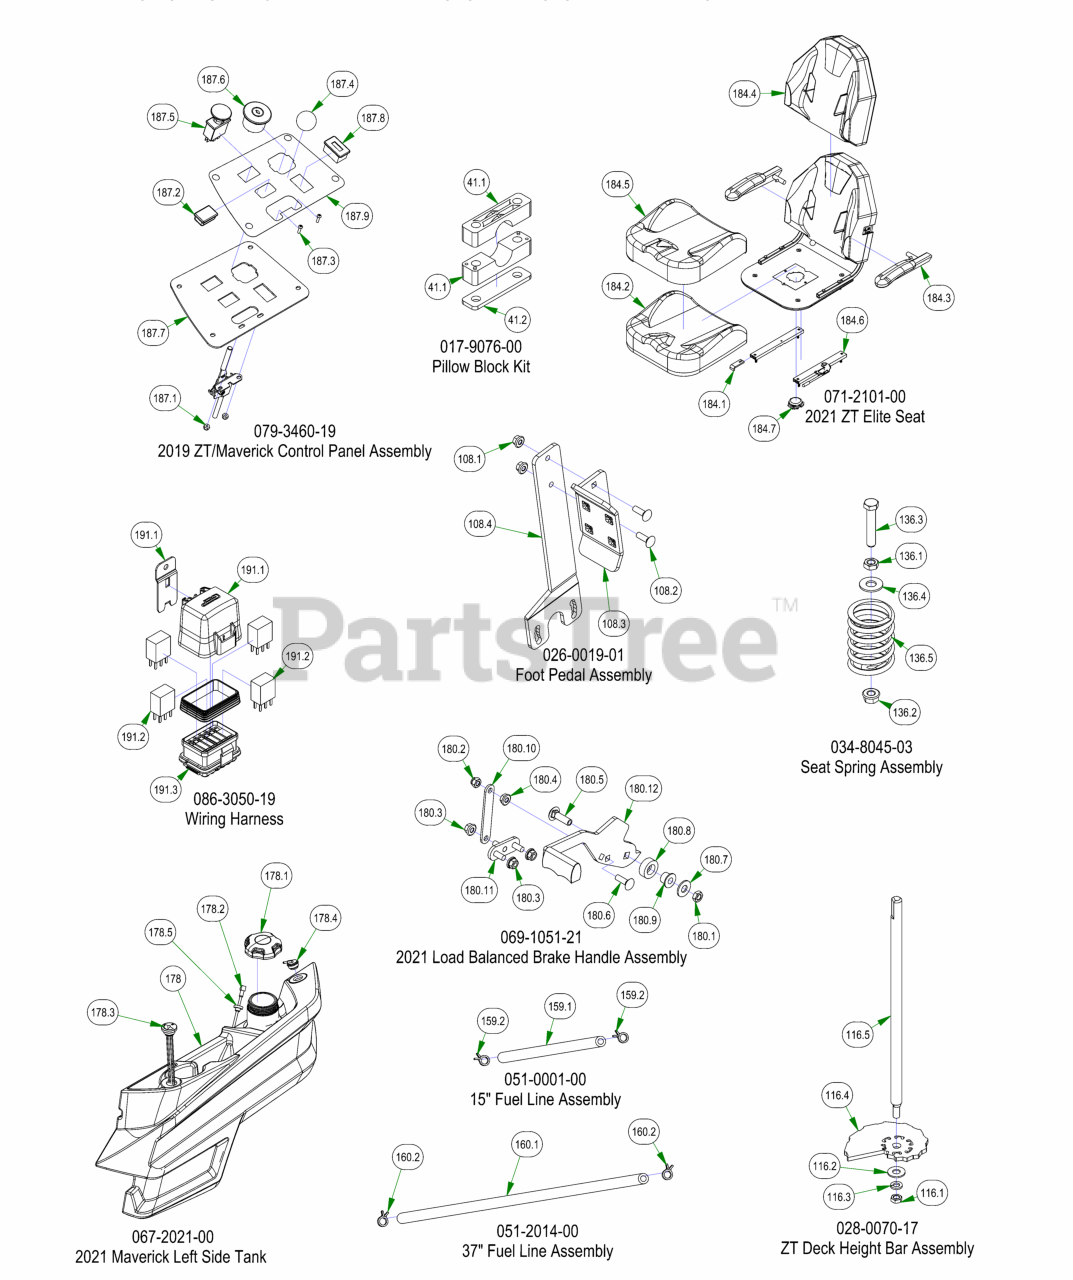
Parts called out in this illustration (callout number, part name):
41	Pillow Block Kit
41.1	Pillow Block MZ
41.2	Pillow Block Strap
108	Foot Pedal Assembly
108.1	5/16-18 NYLON INSERT FLANGE LOCKNUT ZINC
108.2	5/16-18 X 1 CARRIAGE BOLT (GR.8) ZINC
108.3	2017 MZ/ZT Shallow Foot Pedal
108.4	2017 MZ/ZT Deck Pedal Lever
116	ZT Deck Height Bar Assembly
116.1	3/8-24 HEX NUT ZINC YELLOW
116.2	3/8 FLAT WASHER USS (1" OD) ZINC
116.3	3/8 SPLIT LOCKWASHER ZINC
116.4	2017 MZ/ZT Cam Plate
116.5	2017 Deck Height Dial Rod ZT
136	Seat Spring Assembly
136.1	3/8-16 Half Jam Nut
136.2	3/8-16 HEX SERRATED FLANGE NUT HARD/ZINC
136.3	3/8-16 X 2 HEX CAP SCREW (GR.5) ZINC
136.4	3/8 FLAT WASHER USS (1" OD) ZINC
136.5	Seat Spring
159	15" Fuel Line Assembly
159.1	1/4 Fuel Line
159.2	1/4 Fuel Hose Clamp
160	37" Fuel Line Assembly
160.1	37" 1/4 Fuel Line
160.2	1/4 Fuel Hose Clamp
178	2021 Maverick Left Side Tank
178.3	Fuel Gauge w/Grommet
178.4	Rollover Valve W/Grommet
178.5	Pick-Up Grommet
180	2021 Load Balanced Brake Handle Assembly
180.1	3/8-16 HEX JAM 2-WAY REVERSIBLE CENTER LOCKNUT ZINC
180.2	5/16-18 NYLON INSERT CAP LOCKNUT ZINC (BLK CAP)
180.3	5/16-18 NYLON INSERT FLANGE LOCKNUT ZINC
180.4	5/16-18 HEX SERRATED FLANGE NUT HARD/ZINC
180.5	3/8-16 X 1-1/4 CARRIAGE BOLT ZINC
180.6	5/16-18 X 1 CARRIAGE BOLT (GR.8) ZINC
180.7	3/8 FLAT WASHER USS (1" OD) ZINC
180.8	2015 Brake Lever Spacer
180.9	.377 ID X .625 OD X .500 HGT X .880 FLNG DIA X .060 FLNG THK
180.10	Brake Cable Extension Plate
180.11	Brake Load Balancer Lower Weldment
180.12	Load Balanced Brake Handle with Grip
184	2021 ZT Elite Seat
184.1	Black Seat stop from Seat King
184.2	Seat Cover Molded Foam for 071-2040-18/071-5080-18
184.3	2017 ZT/Maverick/2020 ZTElite/Avenger Arm Rest Kit
184.4	Back Cover for 071-2101-00
184.5	Seat Cover for 071-2101-00/071-2102-00
184.6	Seat Rails for Outlaw Seat/2020 ZT Elite/ZTAvenger
184.7	13/14 MZ/Outlaw Seat Switch
187	2019 ZT/Maverick Control Panel Assembly
187.1	10-24 Nylon Insert Locknut Zinc Orange Nylon
187.2	Light Plug
187.3	10-24 X 5/8 BS Button Head Bolt
187.4	Throttle Lever Assembly
187.5	PTO Engager
187.6	Ignition Switch
187.7	2014 ZT Control Panel
187.8	Tachometer
187.9	Rambler Instrument Panel Decal
191	Wiring Harness
191.1	Relay Block Cover Replacement Kit
191.3	Wiring Harness
